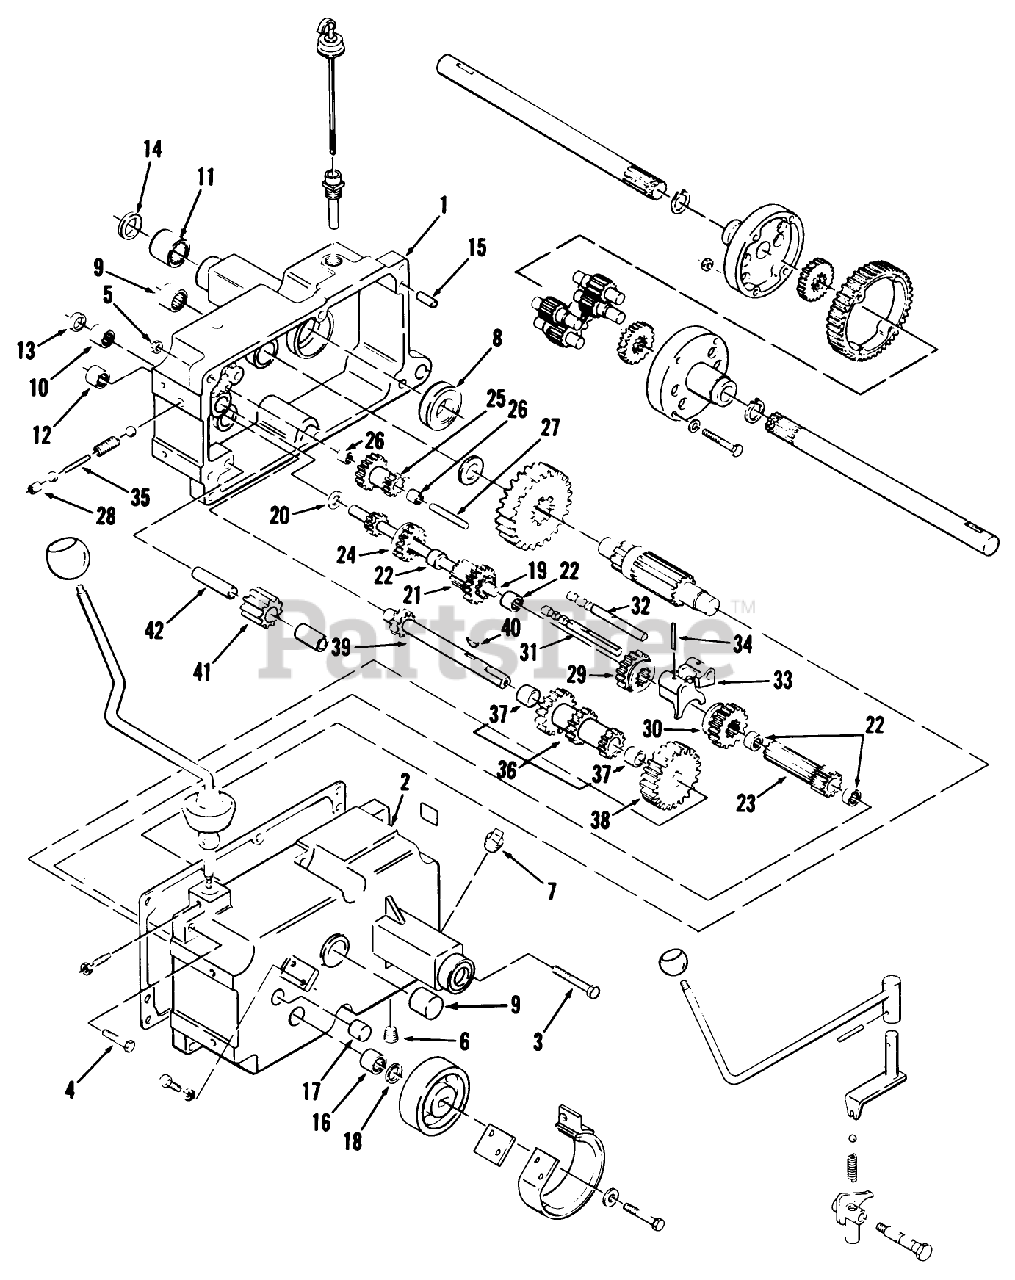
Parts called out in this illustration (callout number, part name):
1	Transaxle Complete
2	CASE-TRANS RH*
4	BEARING-BALL
5	BEARING
6	BEARING-NEEDLE
7	NEEDLE BEARING
8	BEARING-NEEDLE
9	SEAL-OIL
11	PIN-LOCATING
12	END CAP-DIFFERENTIAL
13	GEAR-DIFFERENTIAL RING, 43T
14	GEAR-PINION, 11T
15	WASHER
17	NUT-HEX
20	GEAR-AXLE DIFFERENTIAL
21	RING-SNAP
23	PINION SHAFT
25	WASHER-THRUST
26	SHAFT GEAR
27	GEAR 46 TEETH
31	GASKET-TRANSMISSION
34	SCREW-HH
37	NUT-LOCK, NI
38	NIPPLE-TRANS FILL
41	Repair Manual
